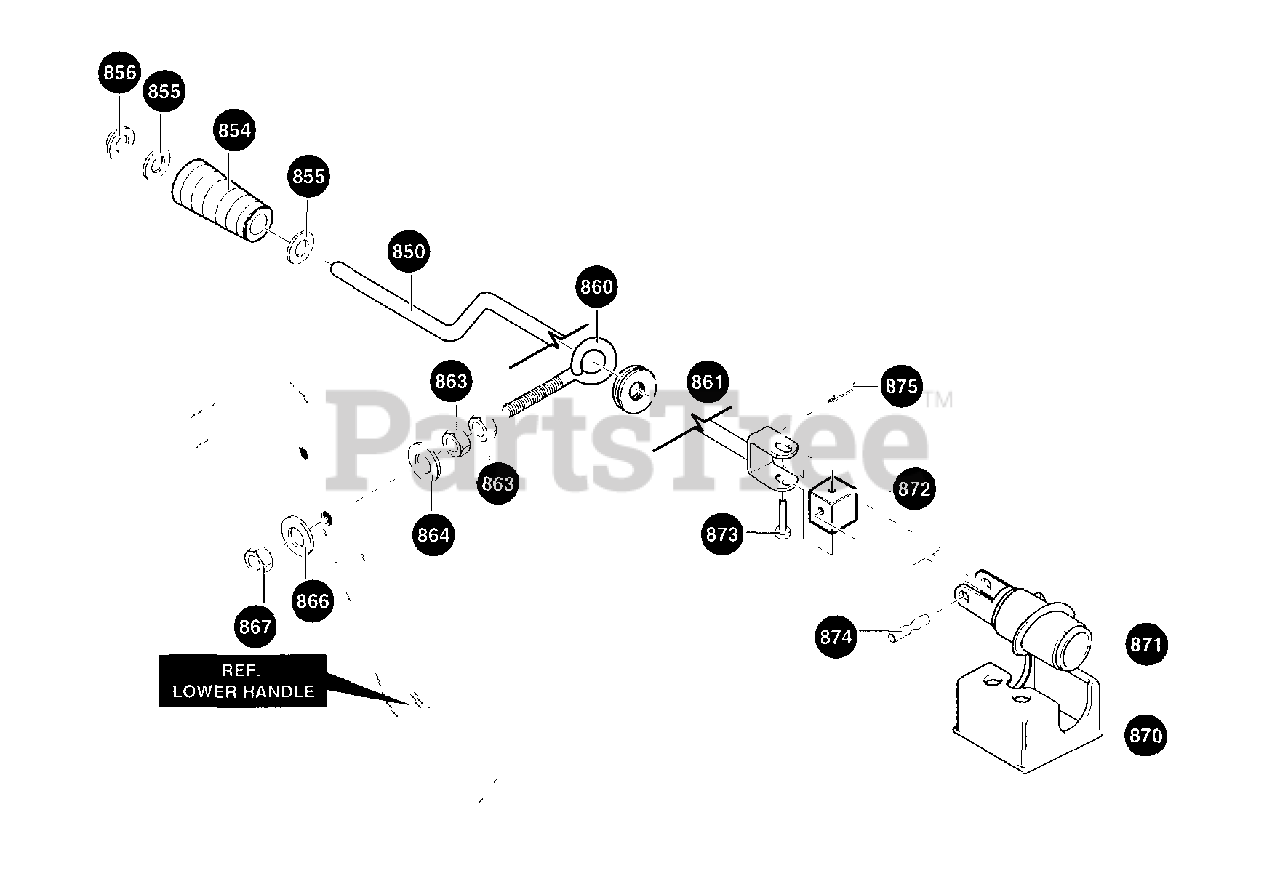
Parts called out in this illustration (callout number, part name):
850	CRANK, ASSY
854	KNOB,SLEEVE
855	FLATWASHER .406 X .81 X .065
856	NUT, PUSH ON
861	GROMMET, EYE BOLT
863	NUT 3/8-16
864	FLATWASHER .406 X .81 X .065
866	FLATWASHER .406 X .81 X .065
867	NUT, 3/8-16 HEXNYL
870	BRACKET, WORM MOUNT
871	WORM GEAR CHUTE ROT
872	BLOCK, UNIV PIV.
873	CLEVIS PIN
874	PIN, UNIV JOINT
875	COTTER PIN
